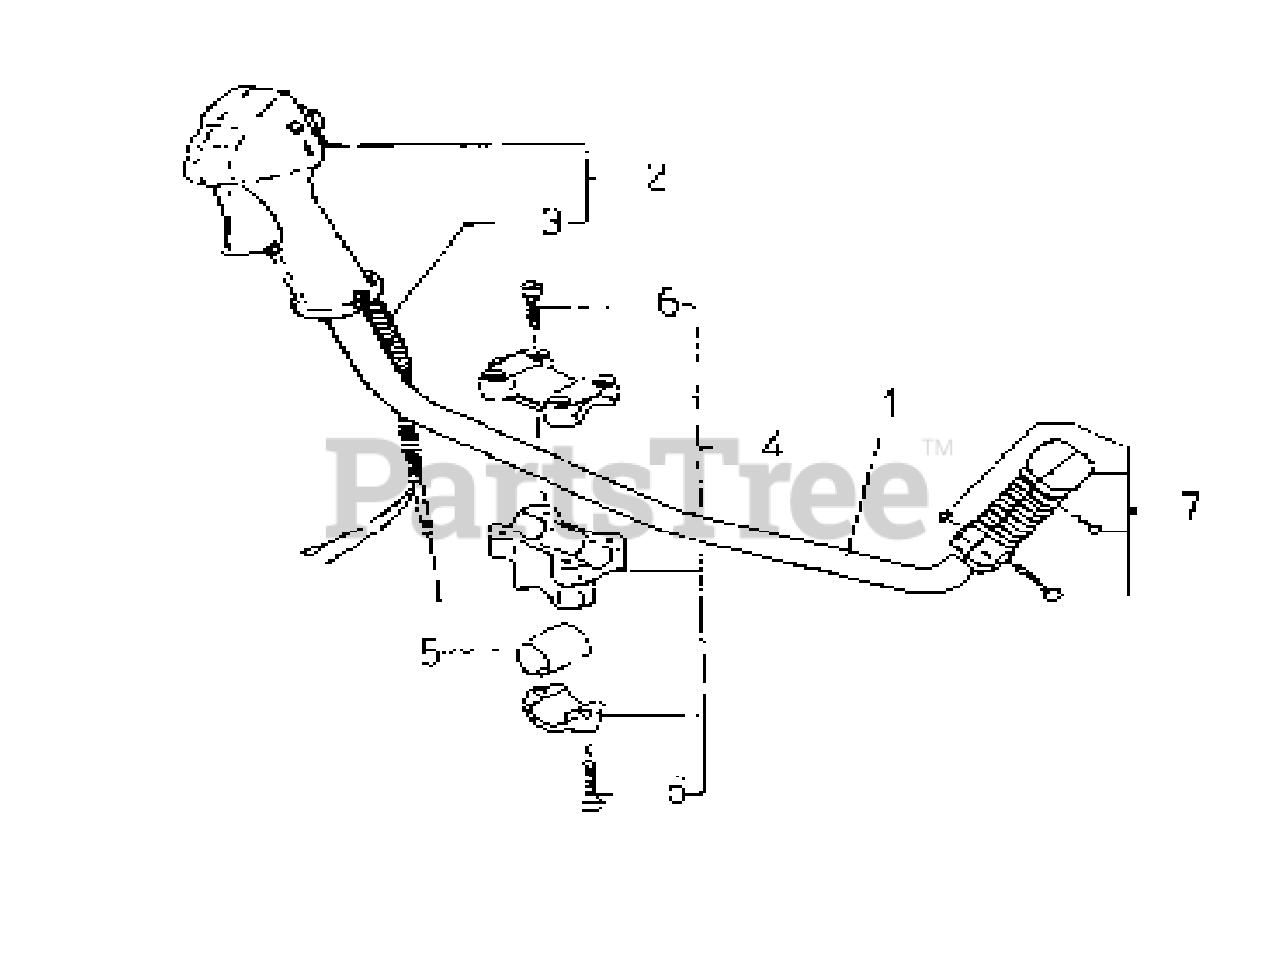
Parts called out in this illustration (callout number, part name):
2	Throttle Lever Assemly
3	Wire, Throttle
4	Holder, Handle
7	Grip Assembly
